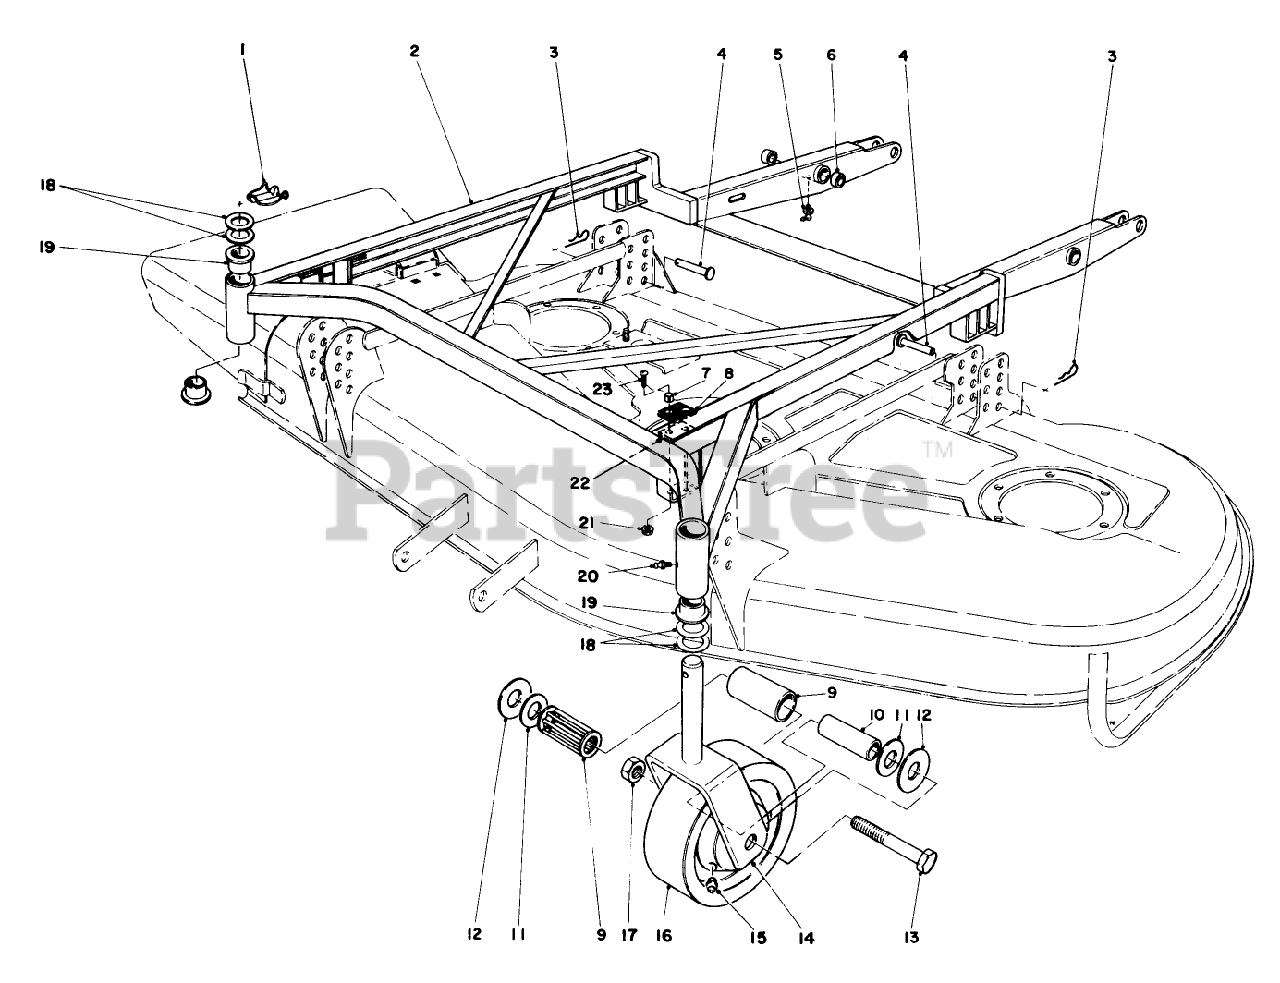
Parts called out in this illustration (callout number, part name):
1	PIN-LYNCH
2	Frame-Deck Suspension (Incl. Ref. #5-6 & 18)
3	PIN-HAIR
4	PIN-CLEVIS
5	FITTING-GREASE, 90 DEG
6	7/8 ID X 1.128 X 7/8 LG BSHG
7	SPACER
8	CUSHION-RUBBER
9	ROLLER BEARING
10	SPANNER BUSHING
11	BEARING RETAINER
12	THRUST WASHER
13	SCREW-HH
14	FORK-Castor
15	FITTING-GREASE
16	Wheel Assy. (Incl. Ref. #9-12)
17	NUT-LOCK
18	WASHER-THRUST
19	Bushing
20	FITTING-GREASE
21	NUT-LOCK, NI
22	SHIM-CUSHION
